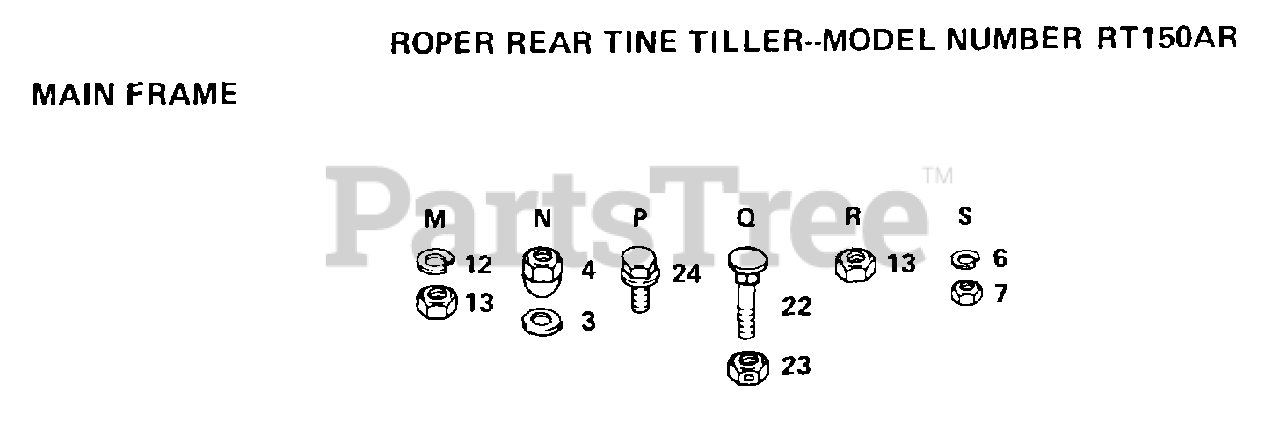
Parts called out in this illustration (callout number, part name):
3	WASHER
4	NUT TI
6	LOCKWASHER
12	LOCKWASHER
13	NUT.HEX.3/8-16UNC
24	SCREW TI
